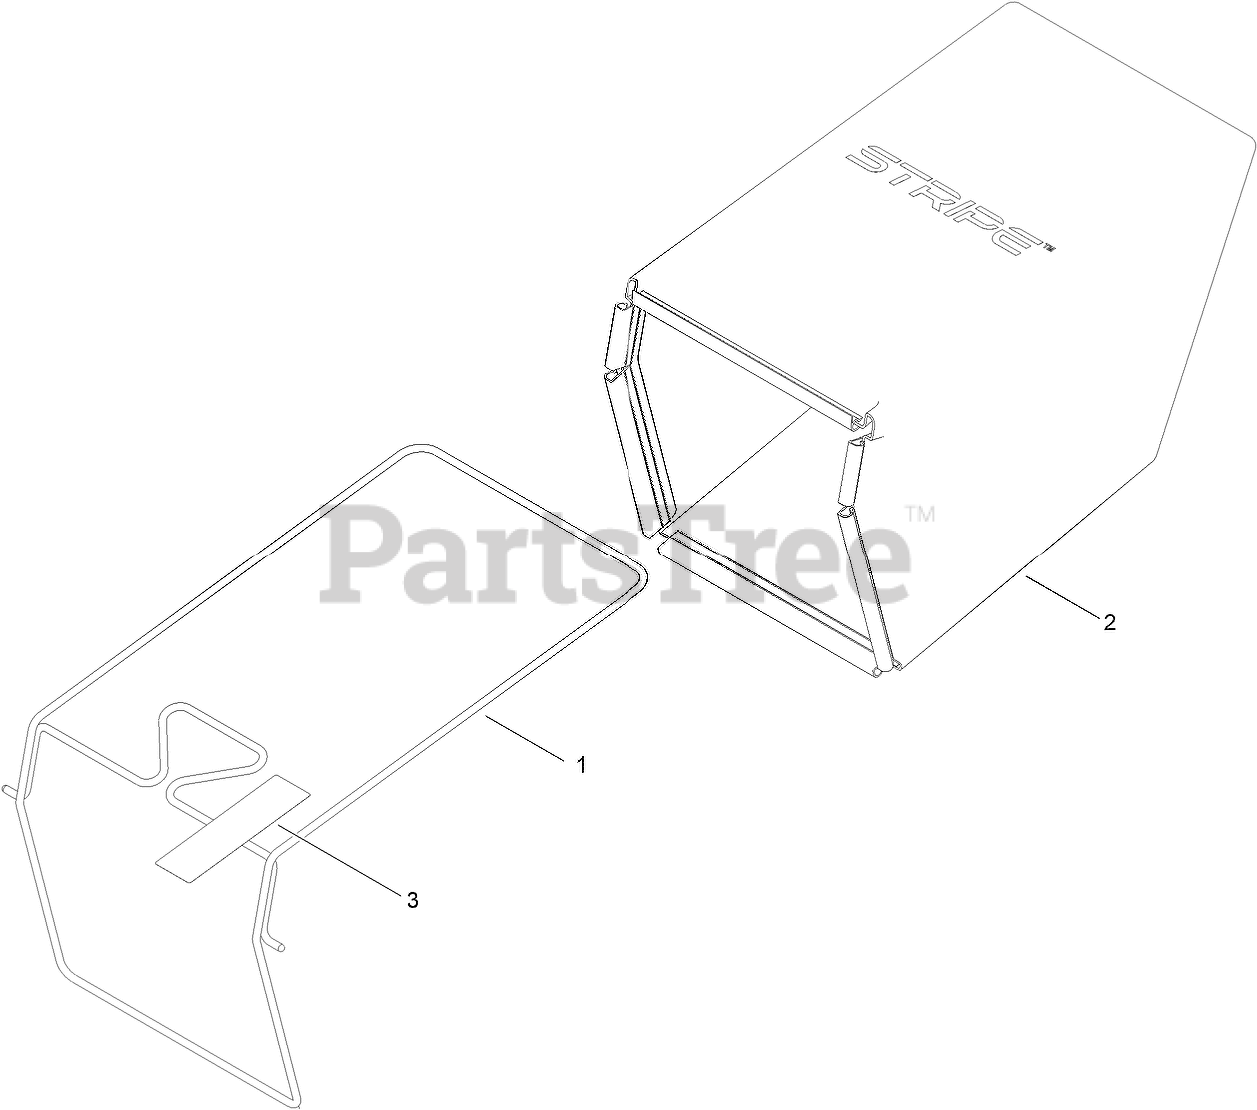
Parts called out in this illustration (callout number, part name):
1	ASM-FRAME
2	ASM-BAG
3	Decal-Warning
